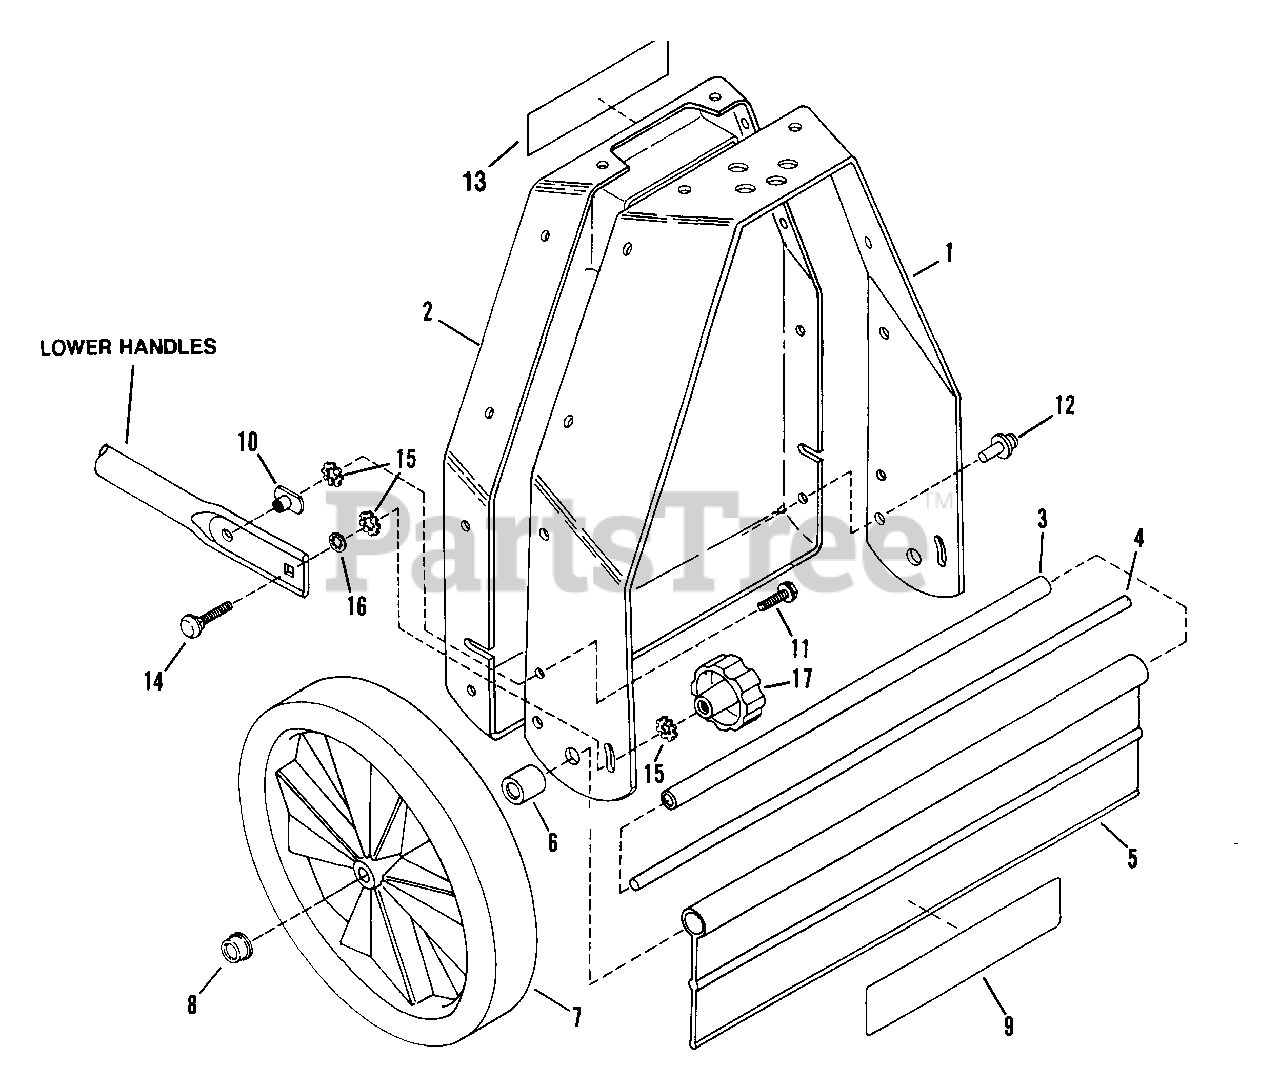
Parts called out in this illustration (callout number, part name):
1	FRAME, Main
2	PANEL, Main Frame
3	SPACER, Tube Frame
4	SHAFT, Axle
5	SHIELD, Trailing
6	BUSHING, Axle
8	NUT, 3/8 Push
9	LABEL, Trailing Shield
10	T-NUT, 5/16-18
11	BOLT, 5/16-18x1/2" Hex Flange Lock
12	RIVET, Plastic
13	LABEL, Adjustment
14	BOLT, 5/16-18x1-1/2" Short Neck Carriage
15	WASHER, 5/16 Int./Ext. Tooth Lock
16	RETAINER, 5/16 Bolt
17	KNOB, 5/16-18 Plastic
